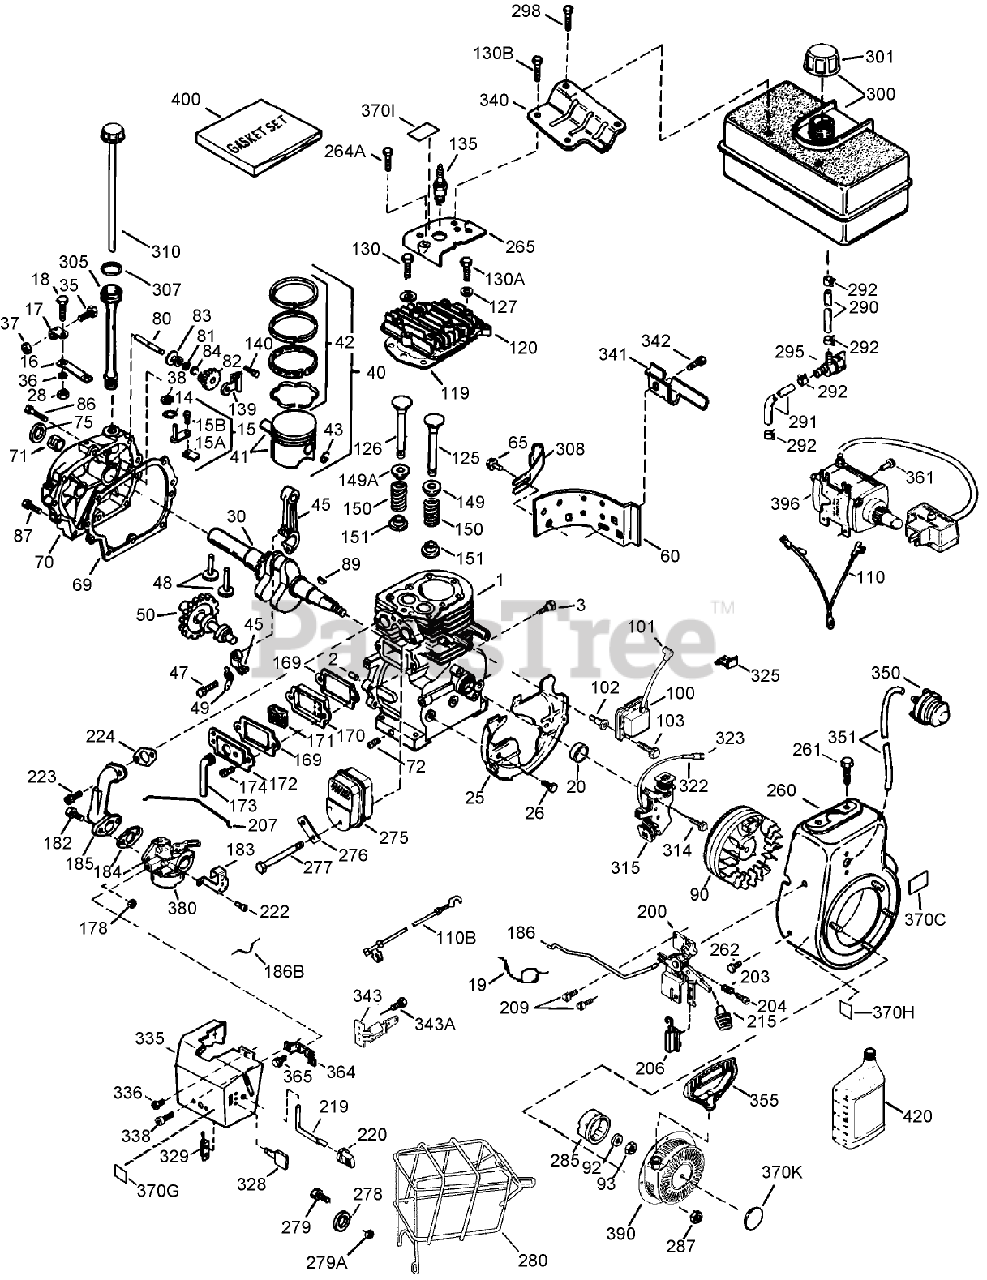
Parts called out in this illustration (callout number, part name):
182	Screw (1/4-28x1)
183	Bracket-Choke
184	Gasket-Carburetor To Intake Pipe
185	Pipe-Intake
186	Link-Governor
186B	Spring-Choke
200	Bracket-Control (Includes 19, 203, 204, 206)
203	Spring-Compression
204	Screw (T-10, 5-40x7/16)
206	Terminal
207	Link-Throttle
209	Screw (10-32 x 1/2)
215	Knob-Control
219	Rod-Choke
220	Knob-Control
222	Screw (10-32 x 1/2)
223	Screw (T-30, 5/16-18x1-3/32)
224	Gasket-Pipe, Intake
260	Housing-Blower
261	Screw (5/16-18x3/4)
262	Screw (5/16-18x9/16)
264A	Screw (1/2-20x5/8)
265	Cover-Head, Cylinder (Black)
275	Muffler
276	62513 SNWTHWR W/284
277	Screw (5/16-18x4-3/16)
278	Washer-Flat
279	Screw (10-16 x 47/64)
279A	washer-Lock
280	Muffler Heat Shield ASM (Includes 278, 279, 279A)
285	Cup-Starter
287	Nut and Lock Washer (1/4-28)
290	Line-Fuel (8.62)
291	Line-Fuel
292	Clamp-Line, Fuel
295	Valve-Shut Off, Fuel
298	Screw (1/4-15x7/8)
300	Tank-Fuel (Includes 292, 301)
301	Cap-Fuel (Black) (1-1/2 I D)
305	Tube-Fill, Oil
307	O-Ring
308	Clip-Tube, Fill
310	Dipstick
314	Screw (1/4-20 x 3/4)
315	Coil-Alternator, 18 Watt (Includes 323)
322	Body-Connector
323	Terminal
325	Clip-Wire
328	Key-Ignition
329	Terminal
335	Cover-Carburetor (Black)
336	Screw (10-32x1/2)
338	Screw (10-32 x 3/8)
340	Bracket-Tank, Fuel (Black)
341	Bracket-Tank, Fuel
342	Screw (1/4-20x19/32)
343	Bracket-Switch, Key
343A	Screw (8-32 x 23/64)
350	Primer ASM
351	Line-Primer
355	Handle-Starter, Mitten Grip
361	Screw (T-30, 1/4-20x15/32)
364	Bracket-Cover, Carburetor
365	Screw (8-32x27/64)
370C	Decal-Primer, International Symbol
370G	Decal-Instruction
370H	Decal-Speed Control and Choke
370I	Decal-Warning (Bilingual)
370K	Decal-Tecumseh Logo for Top of Recoil Starter
380	Carburetor ASM (Includes 184)
390	Starter-Rewind
396	Electric Starter Motor ASM (220 Volt)
400	Gasket Set (Includes 69, 119, 169, 184, 224)
420	Oil-Engine, S A E 5W30
